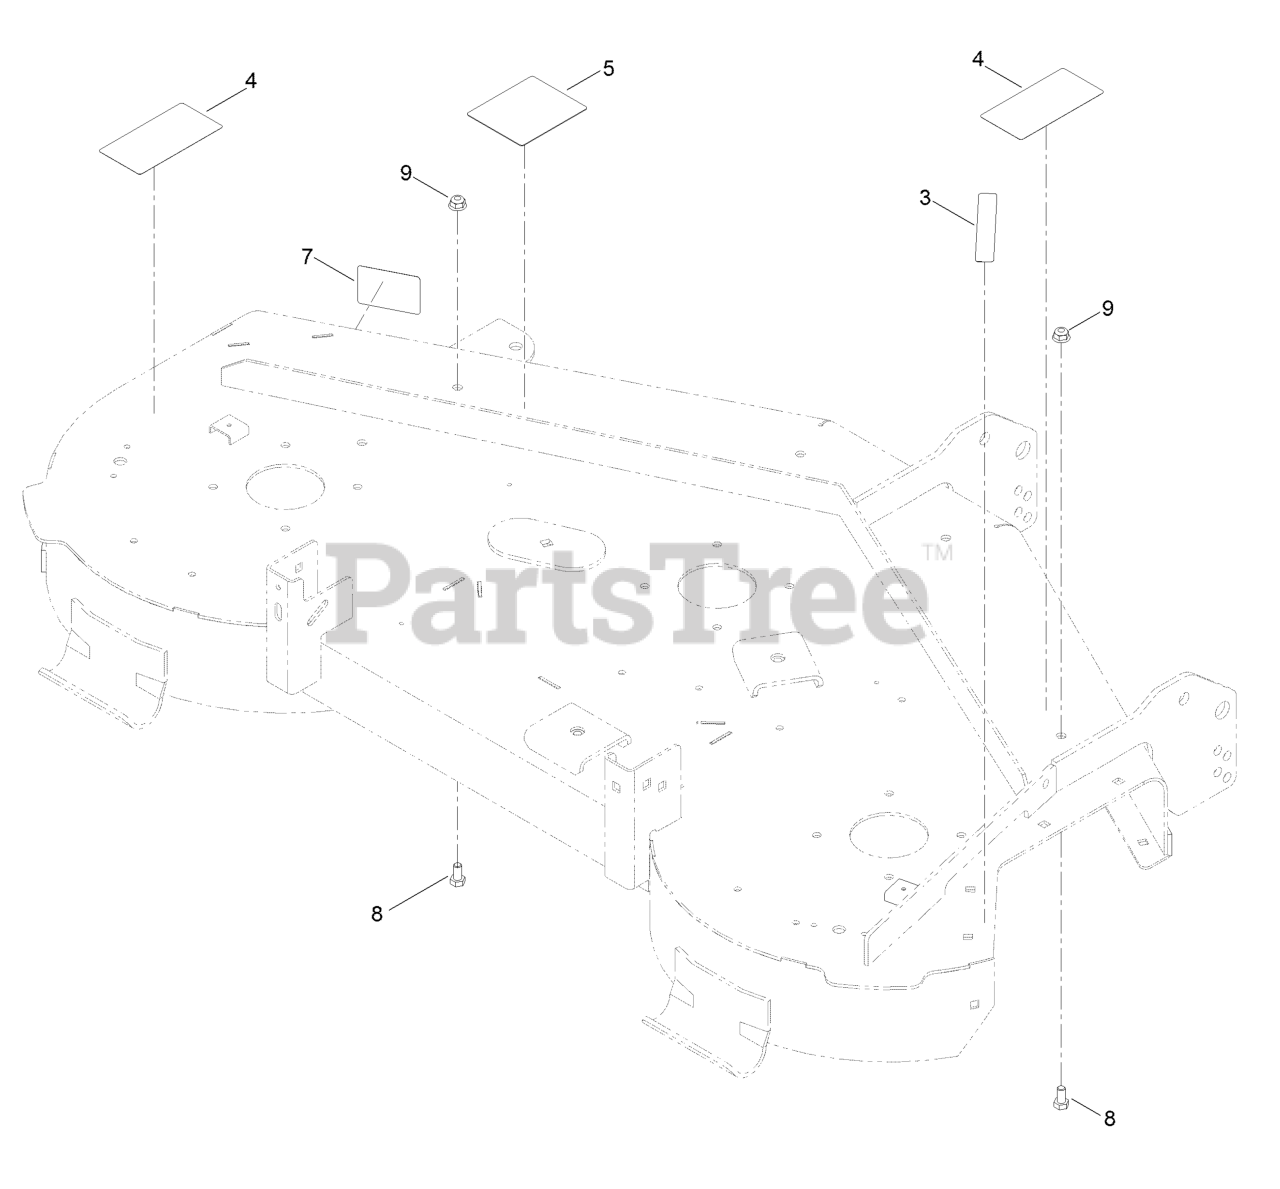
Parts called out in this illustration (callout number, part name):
3	DECAL-DANGER
4	DECAL-DANGER, DECK
5	DECAL-ROUTING, BELT
7	DECAL-SCALP, ANTI
8	SCREW-HH
9	NUT-HF, NI
